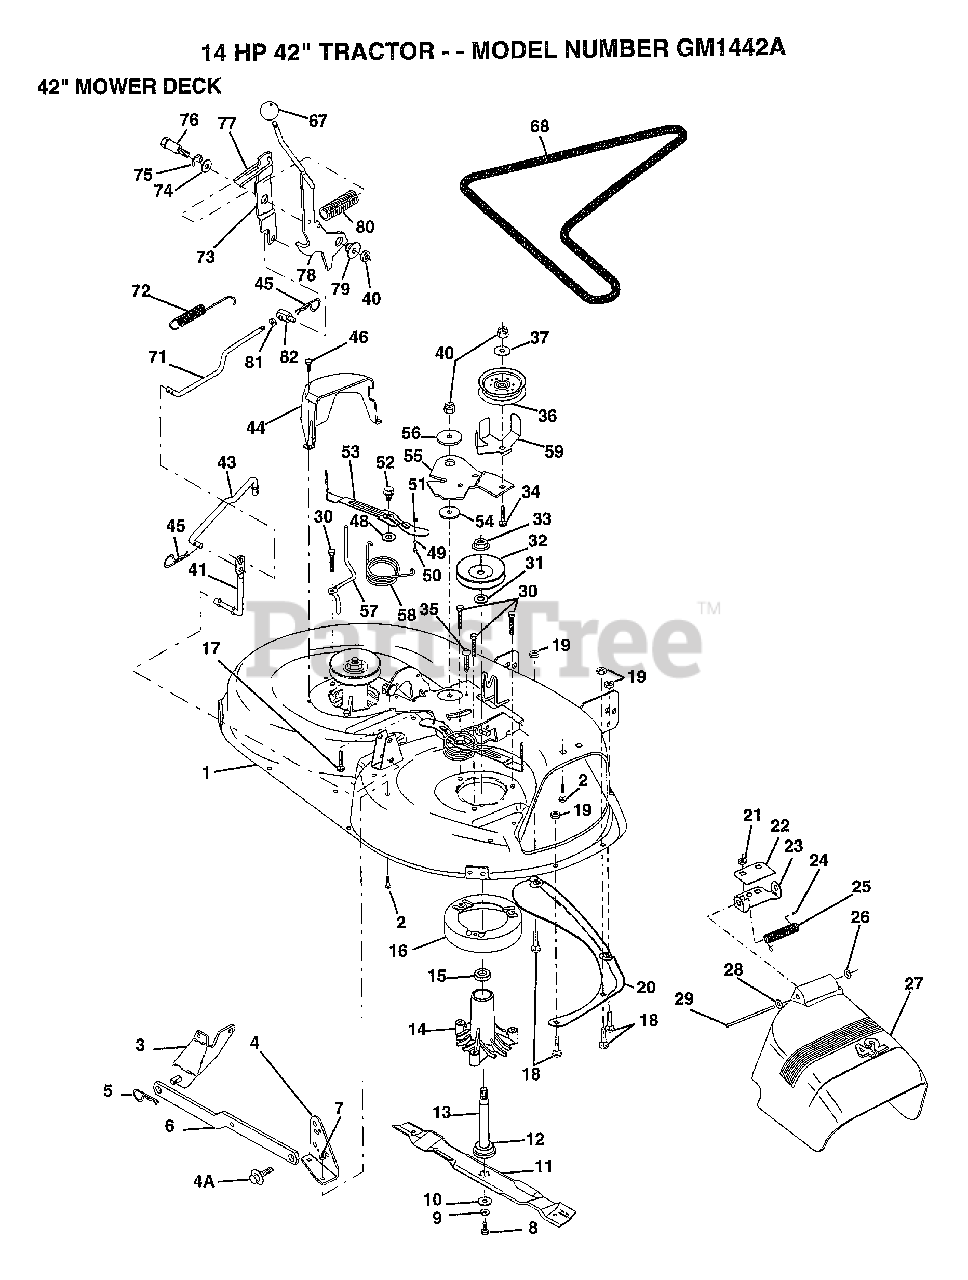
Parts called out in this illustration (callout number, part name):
2	BOLT
3	BRKT ASM SWAY BAR
4	BRKT DECK SW BAR
4A	BOLT SHD 5/16-18
7	NUT
8	BLADE BOLT
10	WASHER.HARD.BLADE
11	"BLADE.42"" MULCHER"
12	BEARING.BALL
14	HSG ASM MANDREL
15	BEARING
16	STRIPPER RND MWR
17	BOLT RDHD 3/8-16
18	BOLT
19	NUT
21	NUT
22	STIFFENER BRKT
23	DEFLECTOR BRKT
24	CAP-SLEEVE LT
25	SPRING TORSION
26	NUT PUSH M
27	DEFLECTOR.SHIELD
28	WASHER
29	HINGE ROD
31	WASHER
34	BOLT
35	XMAS TREE FASTNER
36	FLAT IDLER PULLEY
37	WASHER
40	NUT
41	PIVOT ROD
43	ROD CLUTCH W/NIBS
44	GUARD MAND LH BLK
45	RETAINER M
46	SCREW.1/4-20X5/8
48	HARD SMALL WASHER
50	SHOULDER BOLT
51	LOCKNUT
52	BOLT.SHLD.5/16-18
53	BRAKE PAD ARM ASM
54	HARDENED WASHER
56	SPACER RETAINER
57	KEEPER BELT LH 42
58	SPRING TORSN BRAK
59	GUARD IDLER TUV
67	KNOB T(3/8 HOLE)
68	BELT-V MWR 82.625
71	ROD CLUTCH 38/42
72	RETURN SPRING
73	CLUTCH ARM SECOND
74	WASHER
75	RING
76	SHOULDER BOLT
77	SPRING KEEPER
79	BUSHING
81	NUT
82	TRUNION ADJ
